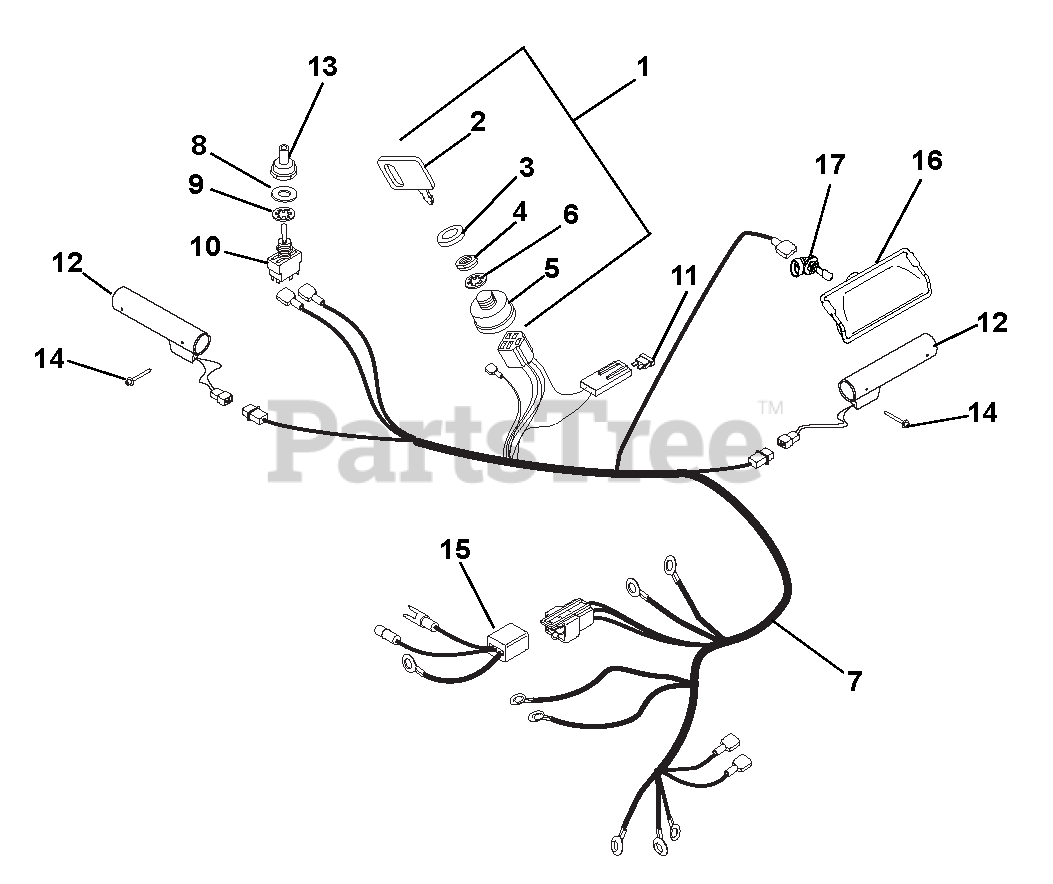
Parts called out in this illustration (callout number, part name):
1	SWITCH ASSEMBLY
2	KEY -W/CAP
3	CAP - IGNITION SWITCH
4	NUT-PANEL .625-32 GRECO
5	IGNITION SWITCH ASSEMBLY
6	WSHR-LK-INT .625X.045 YWZC
7	HARNESS, LIGHT & WARMER
8	WSHR-FL-STL .505X.875X.024 PL
9	WSHR-LK-INT .563X.040 YWZC
10	SWITCH, ON/OFF
11	FUSE, 15 AMP.
12	HEATED GRIP, MAGURA
13	BOOT, SWITCH
14	RVT-POP #43 .125X.313 STL ZINC
15	HARNESS ADAPTER, BRIGGS 12V
16	HEADLIGHT ASSY, HALOGEN 20W
17	BULB, LIGHT-HALOGEN 20W
